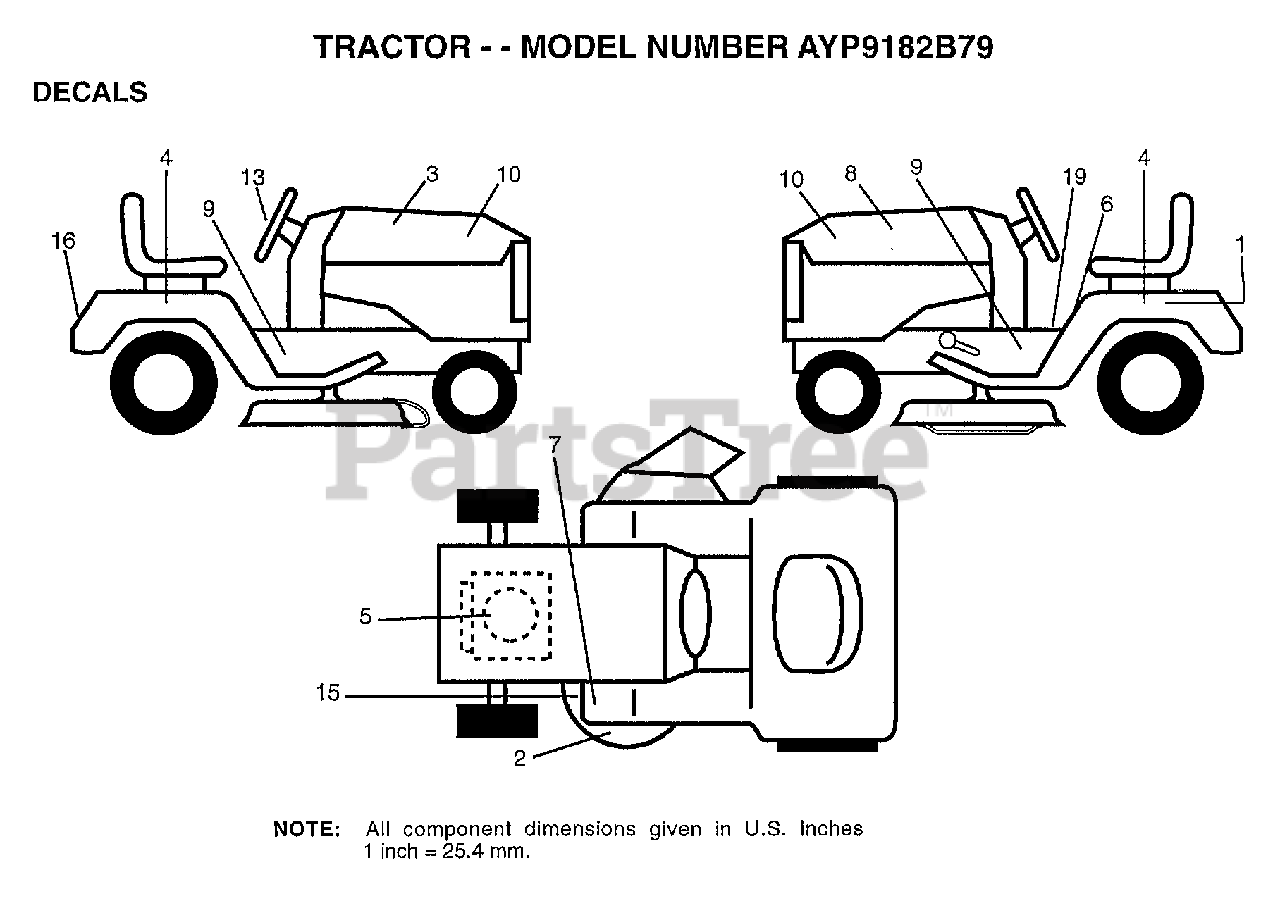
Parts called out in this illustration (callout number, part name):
1	DECAL.BATRY.3-3908
2	DECAL DECK WIZ +
3	DECAL.HD.RH.WIZAR
4	DECAL.FENDER.WIZ
5	DECAL, HP, ENGINE
6	"DECAL DANGER,FEND"
8	DECAL.HD.LH.WIZAR
9	"DECAL.CHASSIS.42"""
10	DECAL INSERT HOOD
13	DECAL.INS.STRG.WL
15	DECAL
19	"DECAL INST,SADDLE"
